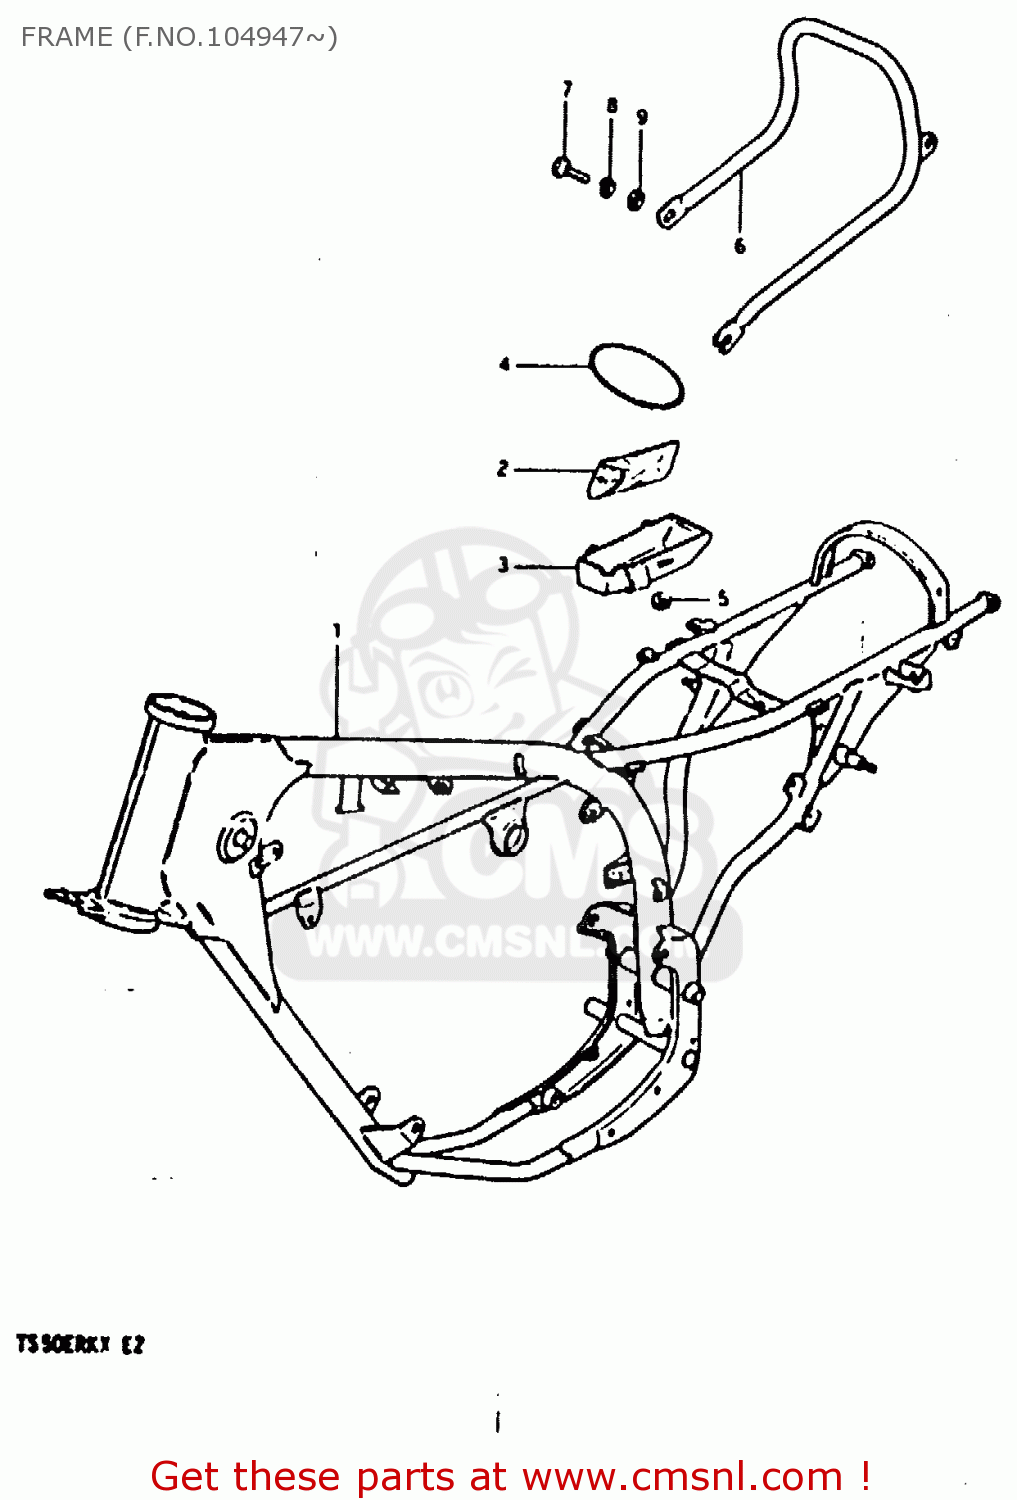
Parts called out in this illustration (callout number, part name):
1	FRAME (BLACK)
2	TOOL ASSY
3	HOLDER, TOOL
4	O RING(D:3.5,ID:76)
5	CUSHION
